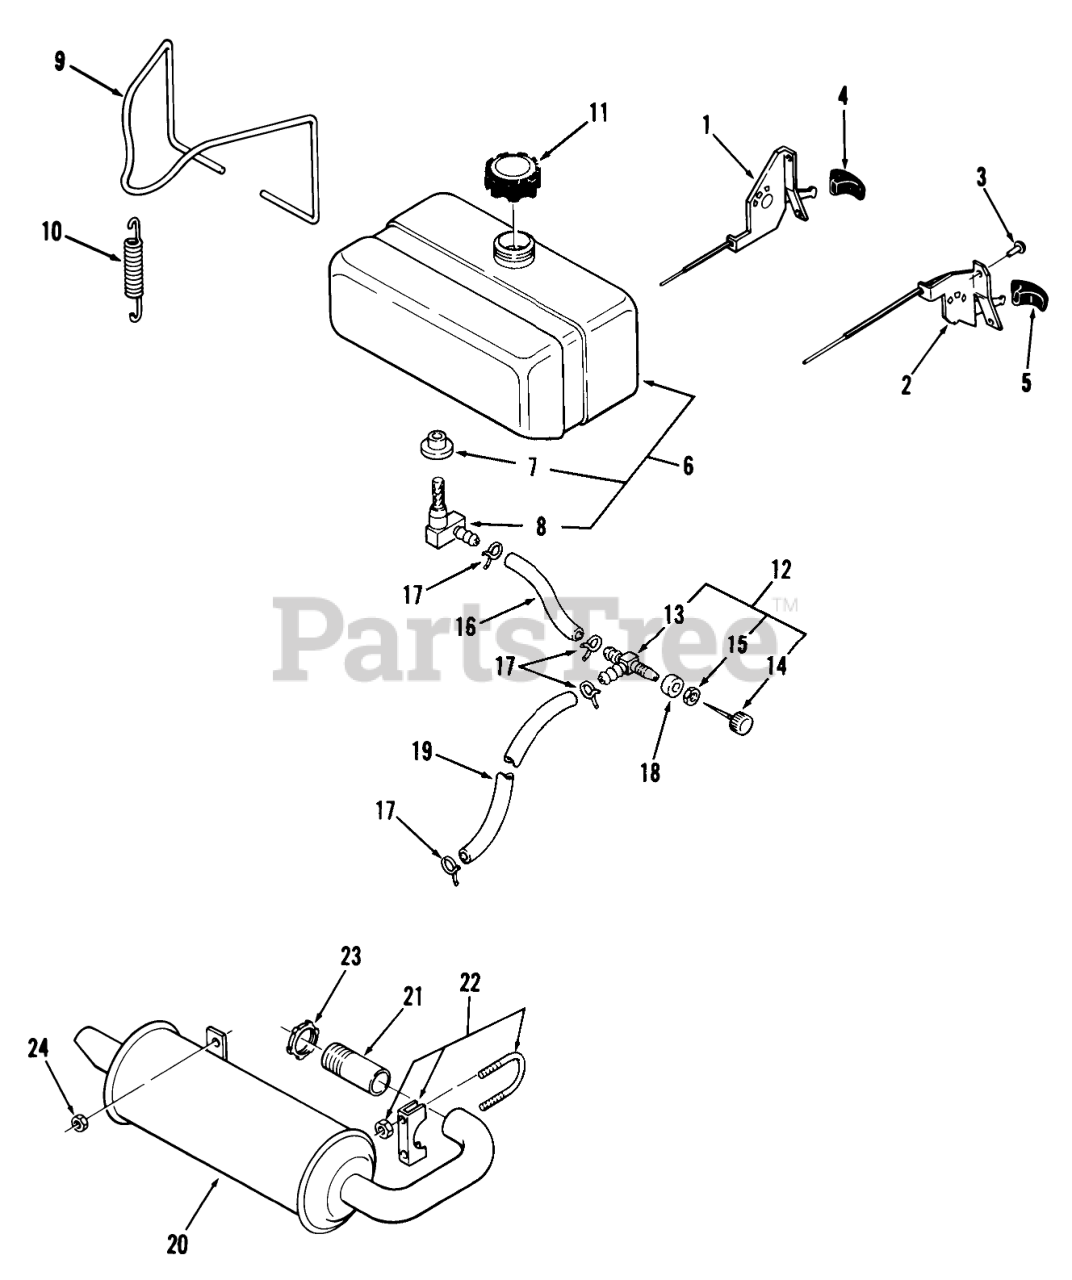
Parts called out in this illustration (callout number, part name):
1	Throttle Control
2	CONTROL-CHOKE
3	RIVET-4
4	KNOB-THROTTLE
5	KNOB-CHOKE
6	ASSY-FUEL TANK
7	BUSHING
8	FITTING FUEL TANK
9	Hold Down Wire
10	SPRING-EXTENSION
11	Cap
12	S/A FUEL VALVE
13	VALVE BODY
14	STEM
15	NUT
16	Fuel Hose 4.5"
17	Clamp
18	SPACER
19	Fuel Hose 18"
20	Muffler
21	NIPPLE
22	ASSY-MUFFLER CLAMP
23	Lock Nut
24	Flanged Nut
